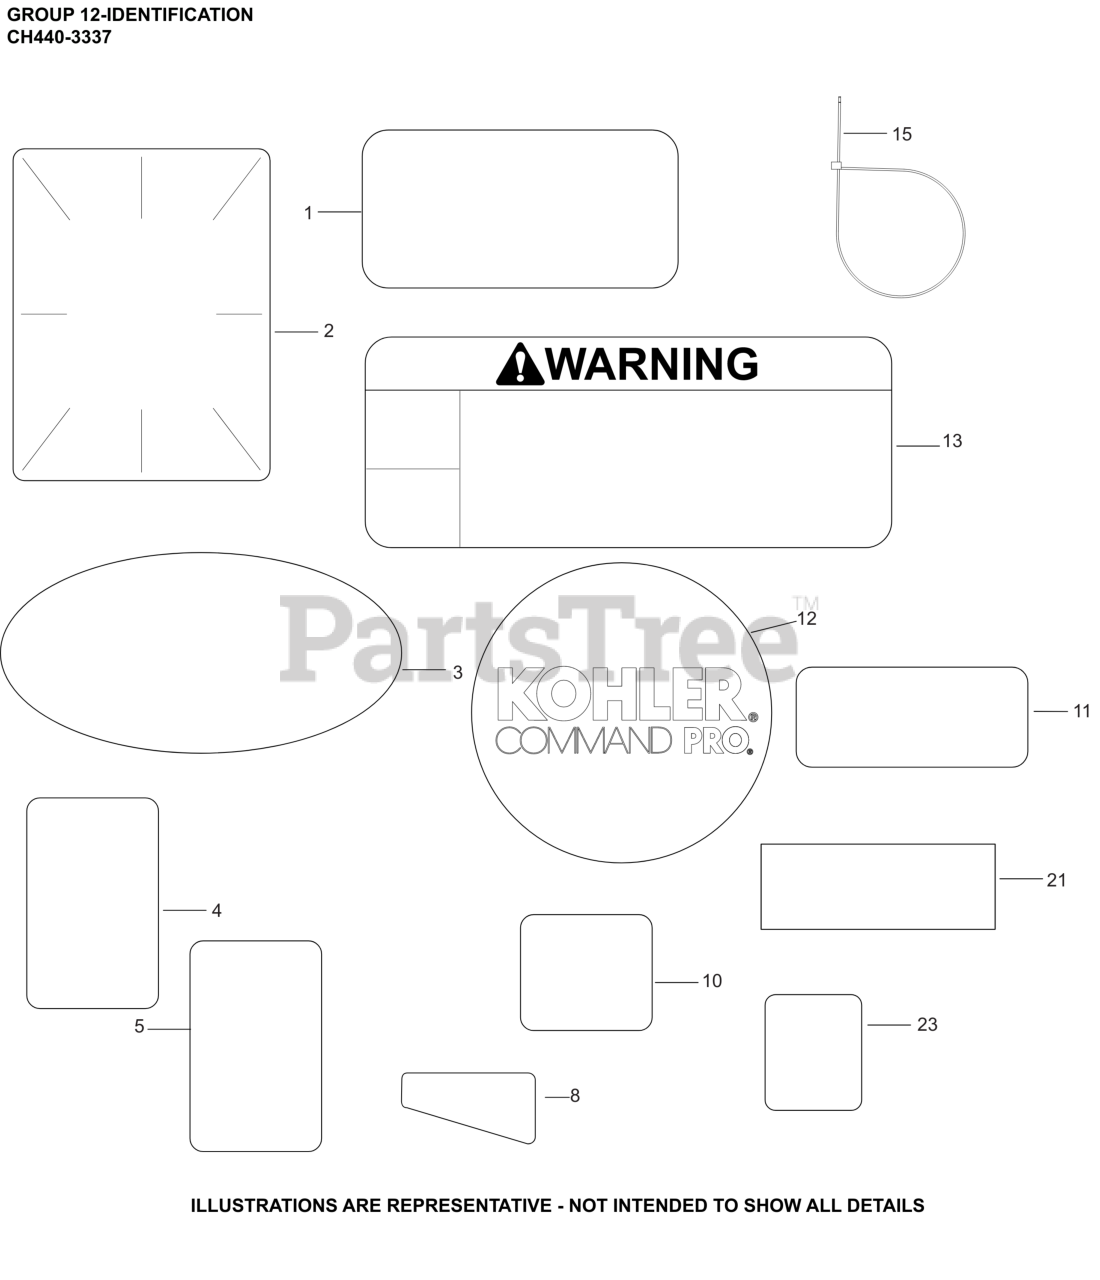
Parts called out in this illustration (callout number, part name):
1	LABEL, MAINTENANCE (CKY)
2	LABEL, CLEAR LAMINATION
3	DECAL, QUAD CLEAN SILVER
4	DECAL, SNOW FLAKE
5	DECAL, SUN
8	DECAL, 14 HP/429cc/CH440
10	DECAL, BASE ARROW
11	LABEL, CANADIAN COMPLIANCE
11	DECAL, ETHANOL WARNING
12	LABEL, RECOIL 75MM
13	DECAL, WARNING
21	DECAL, THROTTLE
23	LABEL, CHOKE
NI	LABEL, FUEL SECURE
